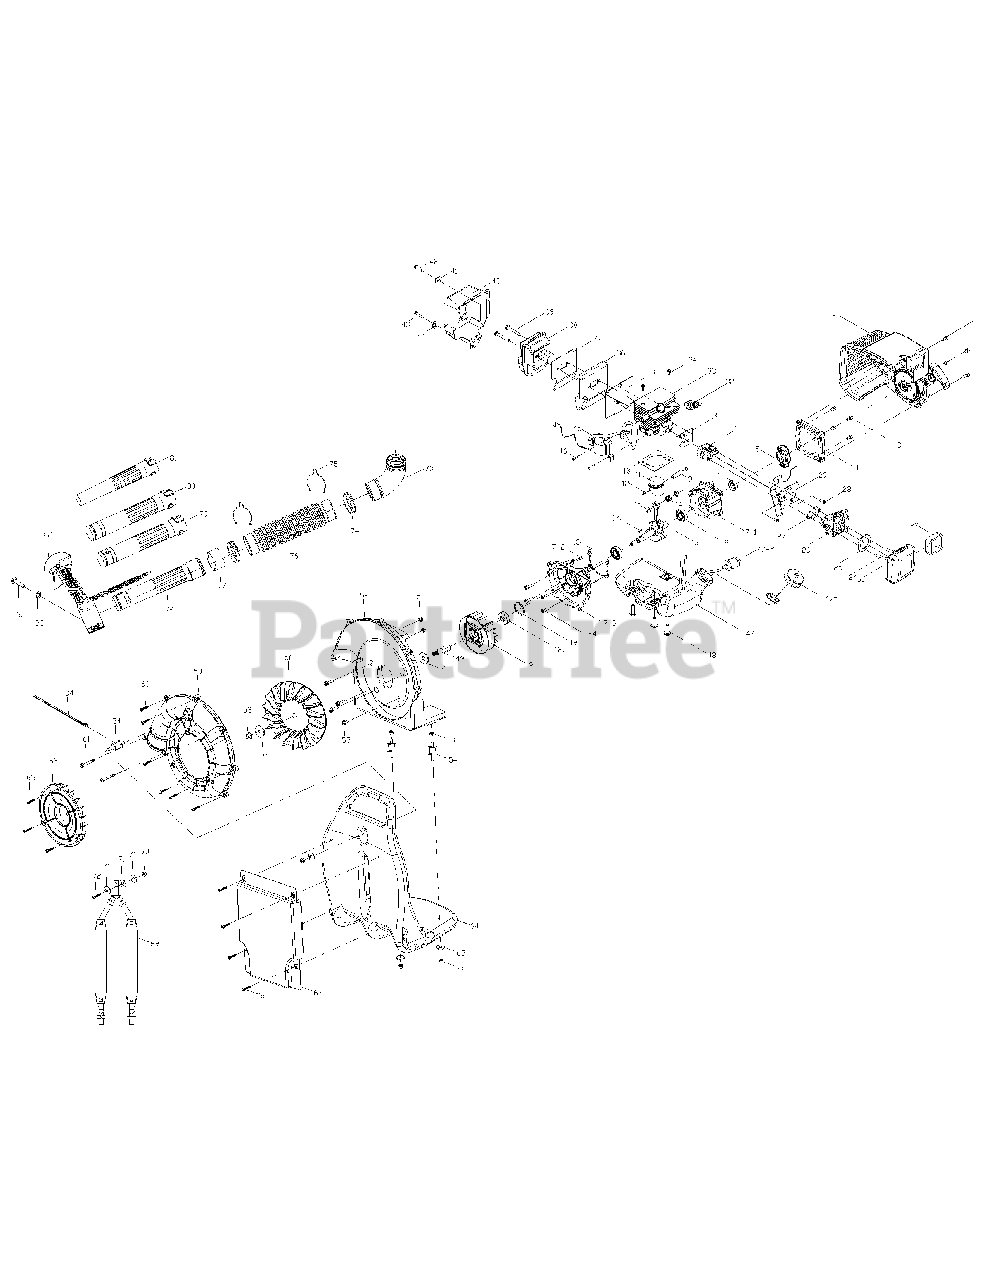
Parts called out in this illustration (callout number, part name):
2	Starter Housing Assembly
4	Connector
5	Pawls Assembly
7	Crank Case Assembly
8	Ball Bearing
11	Piston Ring
13	Gasket, Cylinder
14	Needle Bearing
15	Spacer, Piston
16	Crank/Rod Assembly
17	Key, Flywheel
18	Crank Case Gasket
19	C-Clip
22	Air Cleaner Assembly
23	Filter, Air
25	O-Ring, Air
26	Carburetor
27	Carburetor Gasket
30	Insulator
31	Gasket, Insulator
35	Gasket, Muffler
36	Muffler Heat Shield
37	Muffler Heat Shield
40	Baffle, Muffler
45	Ignition Assembly
47	Fuel Tank Assembly
47-1	Oil Cap Assembly
47-2	Filter, Oil
49	Connect Axis
52	Screw Housing
54	Vibro-Isolating Rubber
56	Impeller 25cc engine
59	Screw Housing
68	Rivet Ribbed
73	Elbow Pipe1
74	Hose Bend
75	Wire Clamp
77	Active Ring
78	Base Pipe
82	Throttle Lever Assembly
84	Ligate Tape
